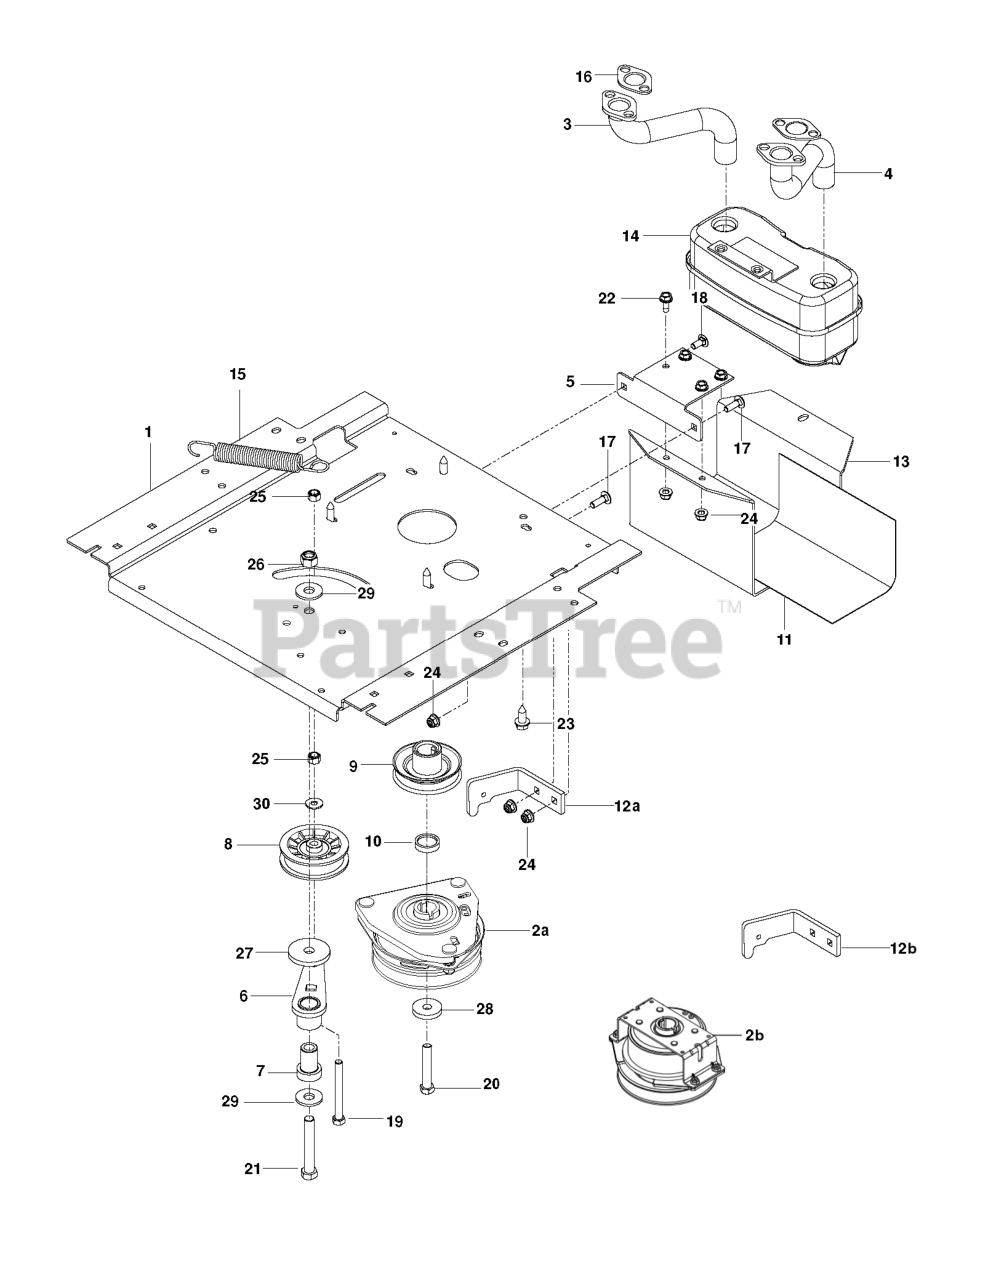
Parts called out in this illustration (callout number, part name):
1	PLATE.ENGINE.PNT.23"FRAME.EDIP
3	EXHAUST.TUBE.RH.B&S.TWIN.INTEK
4	EXHAUST.TUBE.LH.BS/TWIN
5	BRACKET MUFFLER MS431BLK
6	ARM IDLER
7	IDLER SPINDLE
8	PULLEY, IDLER RAKE & ZTR
9	PULLEY.ENGINE
10	SPACER.SPACER.625 W/OGURA.LCC
11	HEAT SHIELD
13	GUARD.MUFFLER.WO.TOW.HITCHX431
14	MUFFLER ASM TWIN
15	SPRING, DECK DRIVE
16	GASKET.MUFFLER
18	RP BOLT 5/16-18 X3/4 ZN/YEL GR
19	HCS 3/8-16X3-1/2 TAPBLT GR5 ZD
20	CLUTCH BOLT7/16-20X2.5 GR524HR
21	HCS 1/2-13 X 3-1/4 GD 5 ZD
22	SCREW.THDROL.5/16-18X3/4.TTY
23	SCREW 3/8-16X1
24	5/16-18 NYLOC FLANGE NUT
25	NUT 3/8-16 NYLOC
26	NUT.LK.W/WSH.1/2.
27	HEAVY WASHER
29	WASHER.9/16 X 1 3/8 X 12 GA.
30	WASHER.5/16.FLAT.STE.STD.
